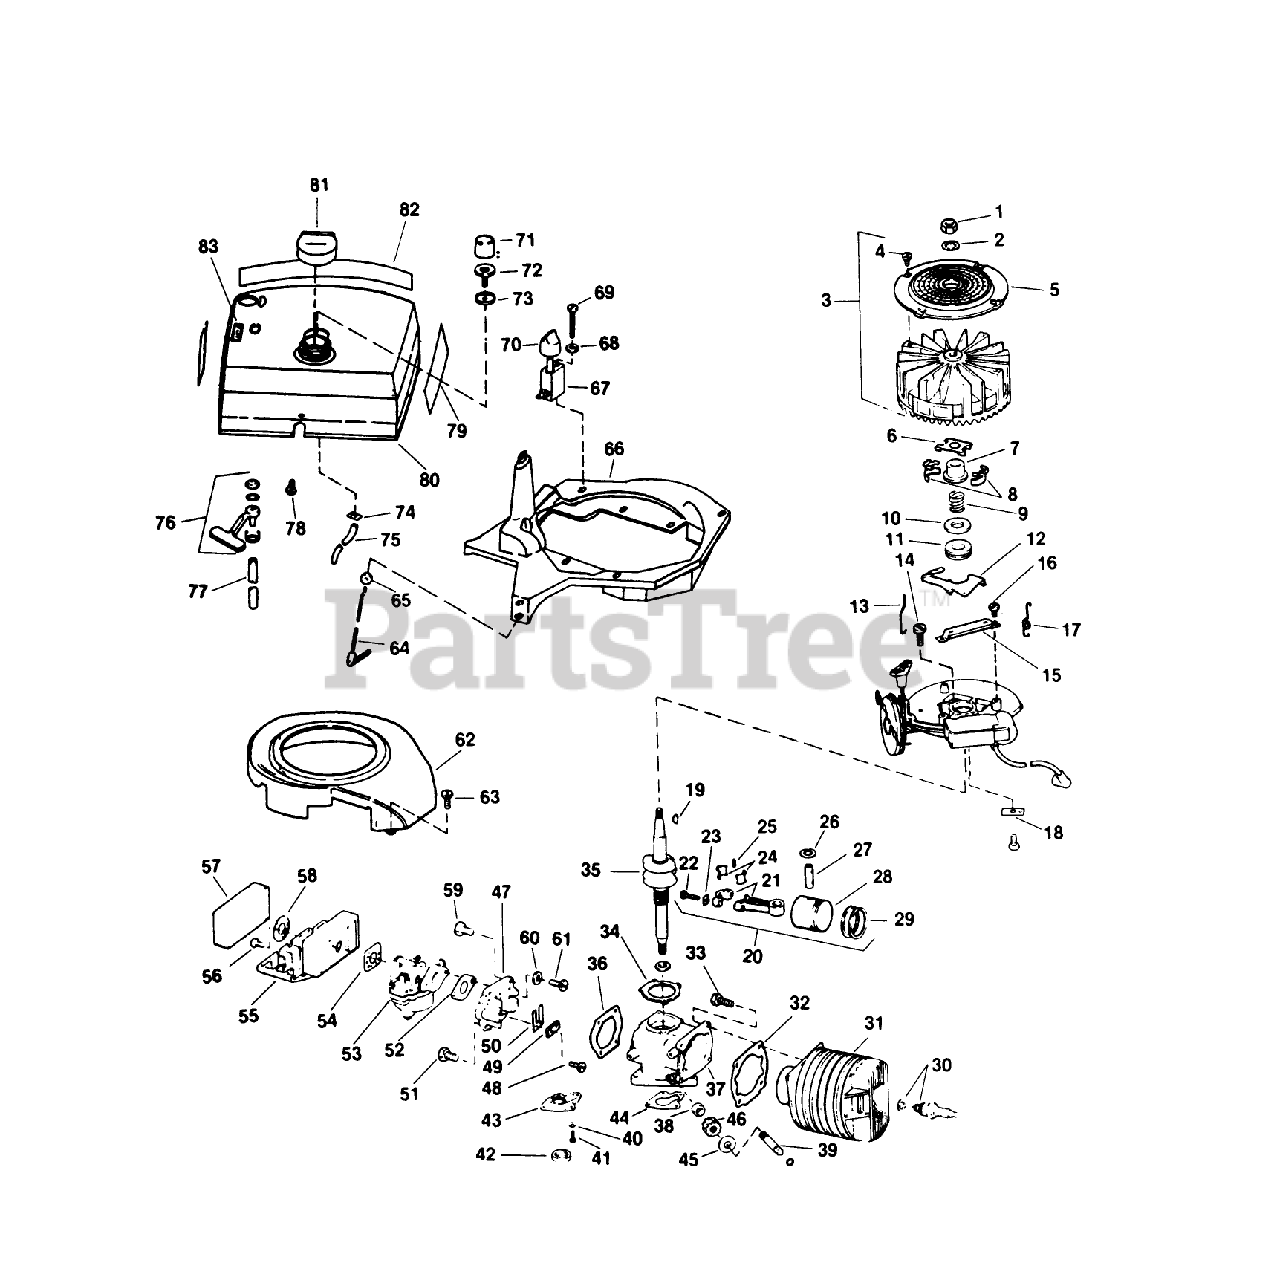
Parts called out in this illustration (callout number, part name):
1	NUT
4	SCREW F
6	YOKE S
7	COLLAR S
9	SPRING S
12	LEVER-GOVERNOR S
13	ROD
14	SCREW S
15	BRACKET
16	SCREW S
17	SPRING
18	TAB
19	KEY
22	SCREW
24	LINER ASM
26	RING-RETAINING
30	Spark Plug
32	GASKET S
34	GASKET S
36	GASKET S
38	SEAL S
41	SCREW
43	GEAR COVER S
44	GASKET-CVR S
45	THRUST WASHER
46	GEAR, DR SHAFT S
47	REED PLATE AY. S
49	PLATE-BACKUP, REED
51	SCREW S
52	GASKET S
54	GASKET S
55	CASE
56	SCREW S
57	AIR FILTER S
58	WASHER S
59	SCREW S
62	BAFFLE
63	SCREW S
65	GROMMET
68	WASHER S
73	CUP-BULB
74	LOCKNUT S
75	TUBING S
78	SCREW S
